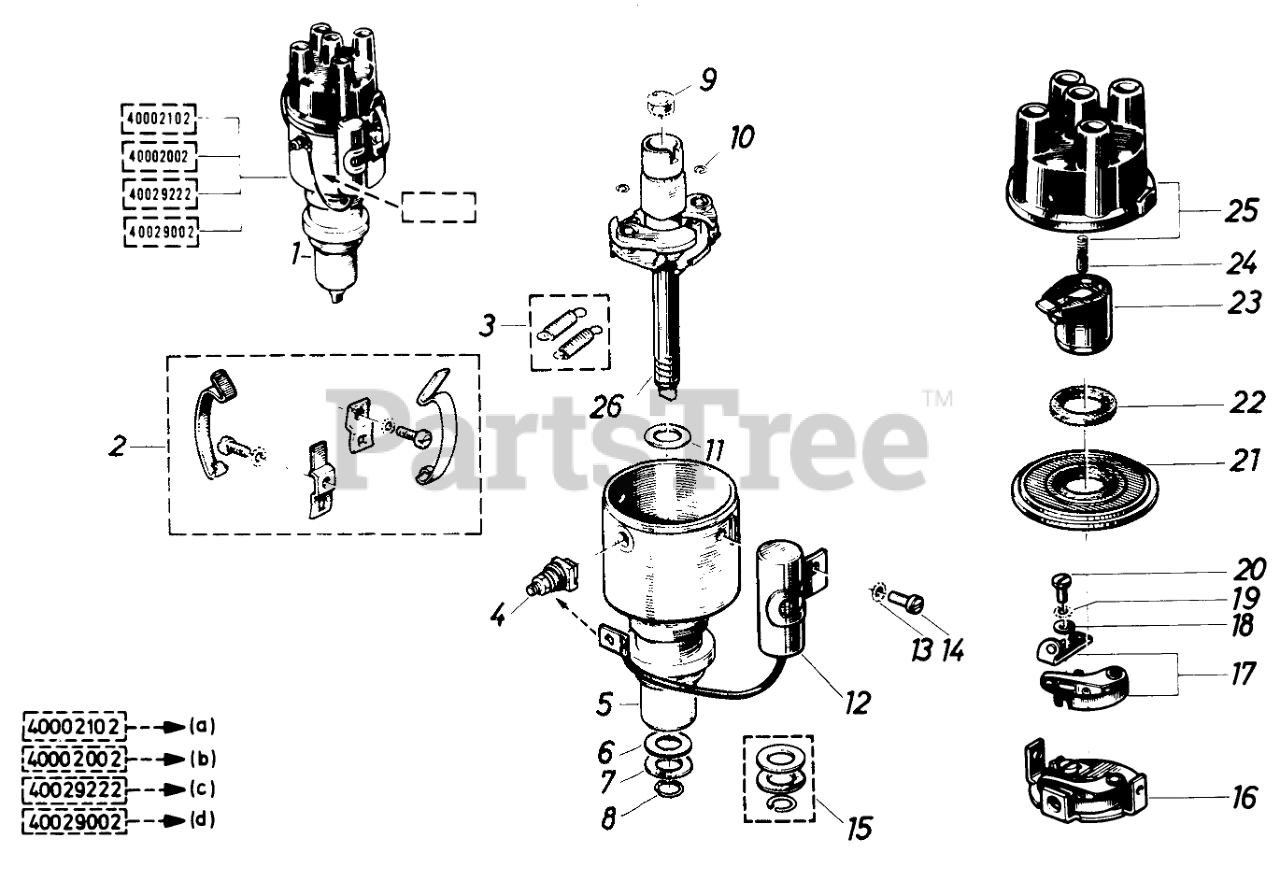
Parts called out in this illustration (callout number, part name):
1	Distributor
2	Retaining Spring Assy.
3	Spring Set
4	Stud and Insulating Bushing
5	Housing
8	Retaining Ring
9	Lubricating Felt
10	Retaining Ring
12	CONDENSER
13	Lock Washer
14	Screw
15	Set of Lock Washers
16	Point Set W/Plate
17	Contact Set
18	Washer
19	Lock Washer
20	Screw
21	Protection Disc
22	Gasket
23	Distributor Rotor
24	Brush with Spring
25	Distributor Cap
26	Cam Shaft and Weights
